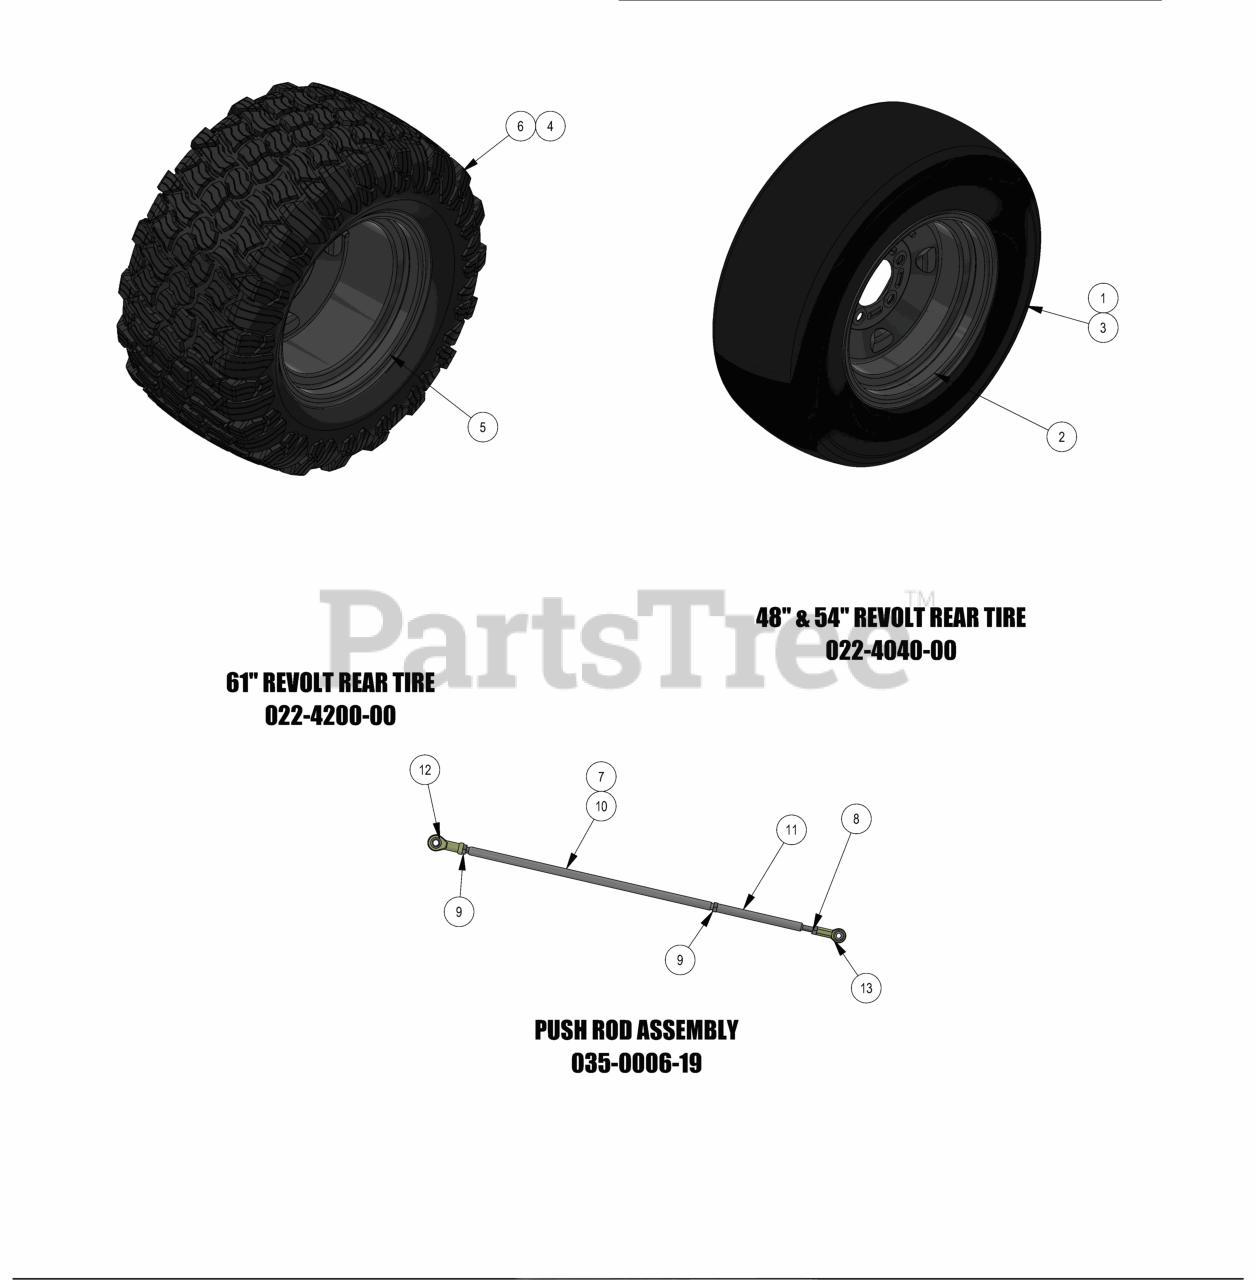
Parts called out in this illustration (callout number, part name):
1	23x9-12 Reaper Turf Tire & Wheel Assembly
2	12x7" Black Wheel
3	23x9-12 Reaper Turf Tire Only
4	23x11-12 Reaper Turf Assembly
5	12x8.5 Black Wheel
6	Tire, 23/11x12 Reaper Turf
7	2019 Revolt Push Rod Assembly
8	5/16 LH Nut
9	3/8-24 HEX NUT ZINC YELLOW
10	2019 Revolt Push Rod
11	2019 Renegade Push Rod Adjuster
12	Spherical Rod End - Outlaw
13	Spherical Rod End - Outlaw
